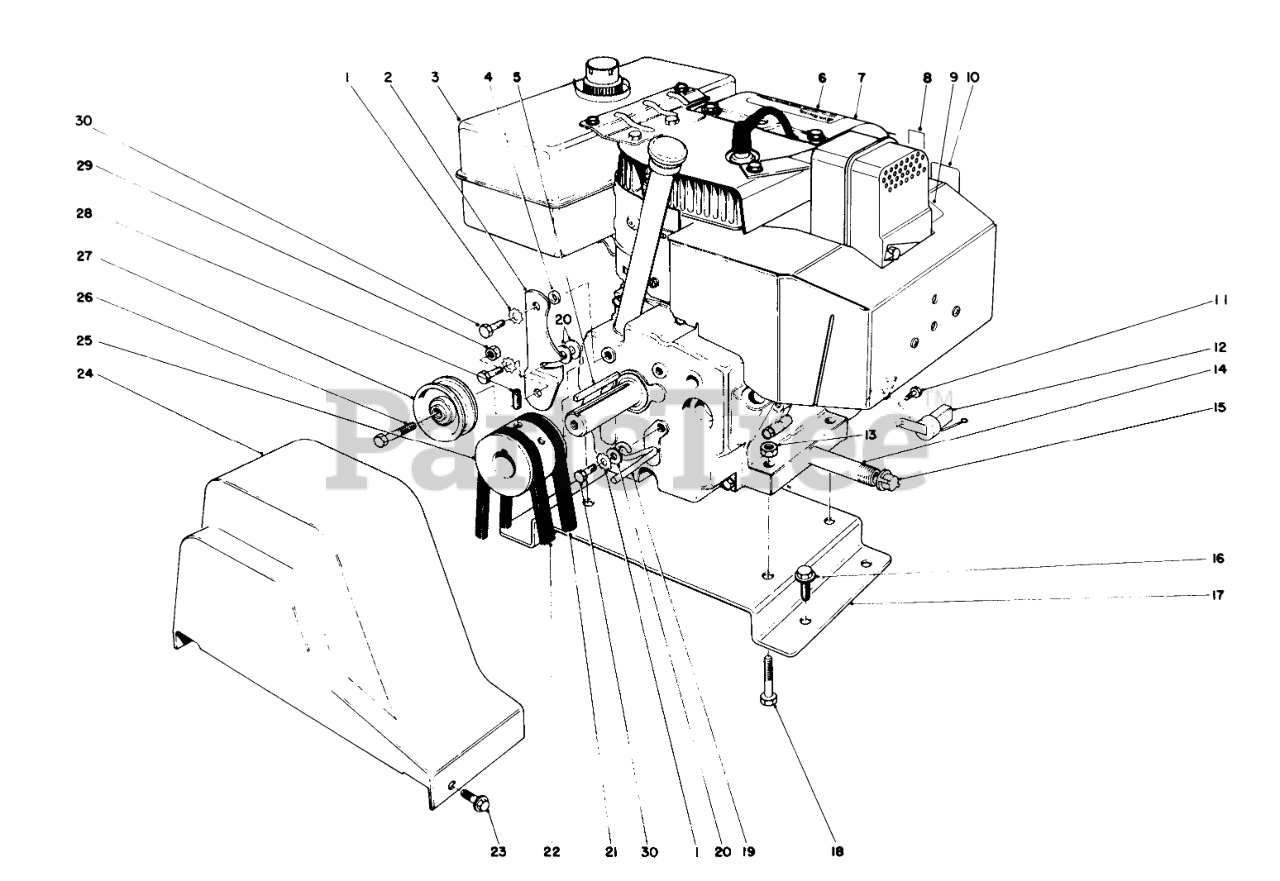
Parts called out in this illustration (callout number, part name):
1	WASHER-LOCK
2	ENGINE IDLER ARM
3	Fuel Tank w/Cap
4	SPACER
6	DECAL - DANGER
8	DECAL-THROTTLE
9	HOT SURFACE DECAL
10	CHOKE DECAL
11	SCREW-HWH
12	INTERLOCK MODULE
13	NUT-LOCK, NI
14	PIPE NIPPLE
15	CAP-PIPE
16	SCREW-HHFTF
17	Plate ngine Mounting
18	SCREW-HH
19	BELT RETAINER
20	WASHER-PLAIN
21	V-BELT
22	V-BELT
23	SCREW-HWH
24	BELT GUARD
25	ENGINE PULLEY
26	SCREW-HH
27	PULLEY-IDLER
28	SETSCREW
29	NUT-LOCK, NI
30	SCREW-HH
